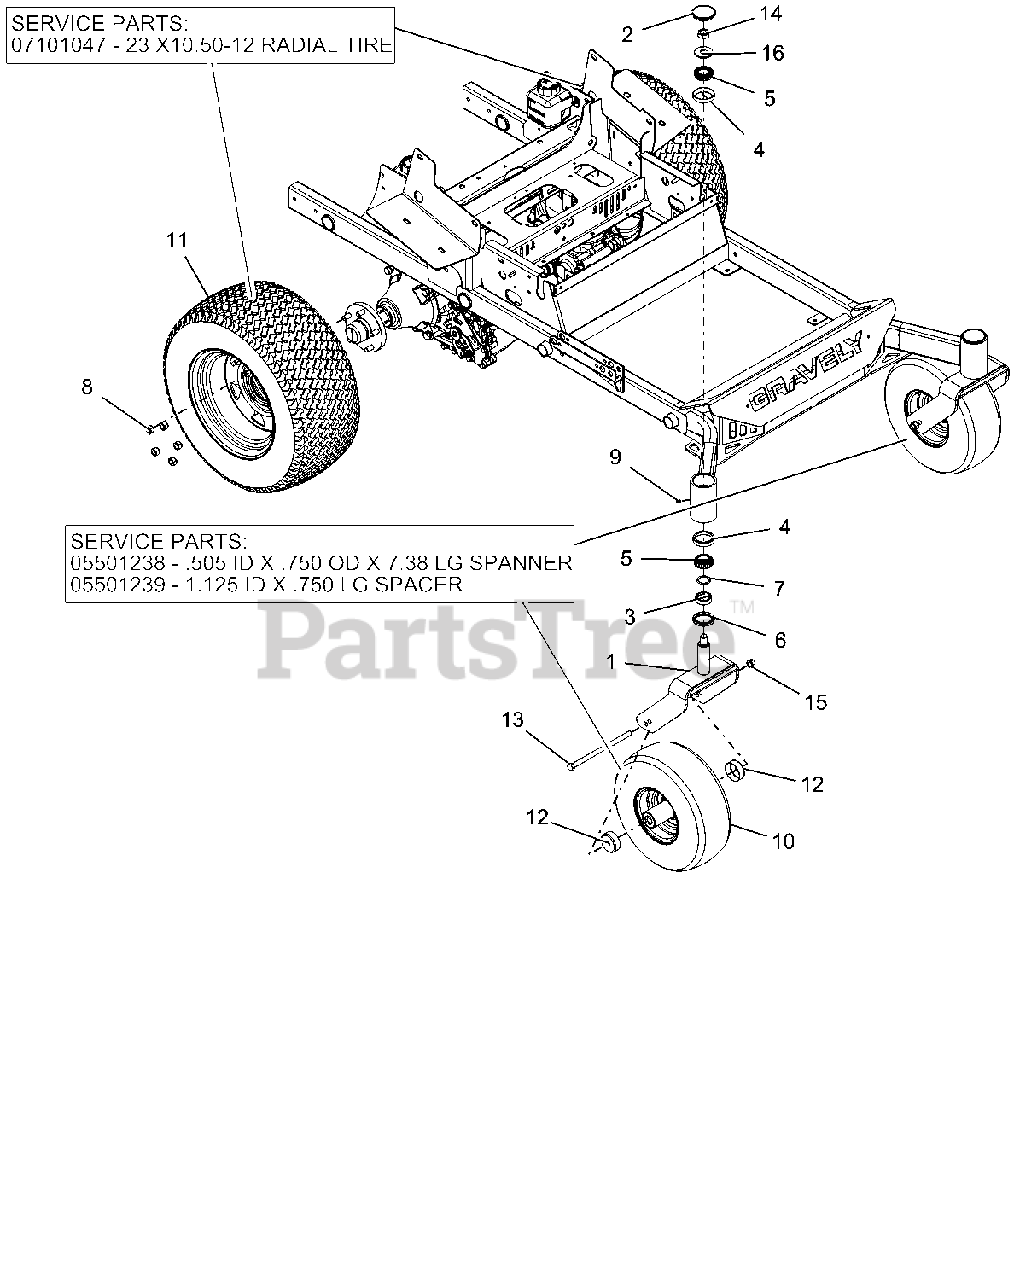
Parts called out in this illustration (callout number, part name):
1	WMT, CASTER FORK - RED
2	CAP, DUST
3	SPCR, FRONT CASTER FORK
4	BRG, CUP 2.328 X .465
5	BRG, CONE 1.250 X .660
6	SEAL, OIL 1.75 X 2.332 X .312
7	O-RING, .139 W X 1.234 ID
8	NUT, LUG .500-13
9	FITTING, .250-28 FLUSH MOUNT GREASE
10	SPANNER, .505 ID X .750 OD X 7.38 LG
10	SPACER, 1.125 ID X .750 LG
10	ASM, WHL/TIRE 15 X 6.00-6 SEMI
11	RADIAL TIRE, 23 X 10.50-12
11	ASSM TIRE\WHEEL, 23 X 10.50 - 12 RADIAL
12	SHIELD, WHEEL BEARING
13	BLT-HEX .50-13X9.00 GR5 YWZC
14	NUT-LK-TOP-JAM .75-16 YWZC
15	NUT, LK-TOP-FLG .50-13 YWZC
16	WSHR-FL-STL.812X2.00X.148YWZC
